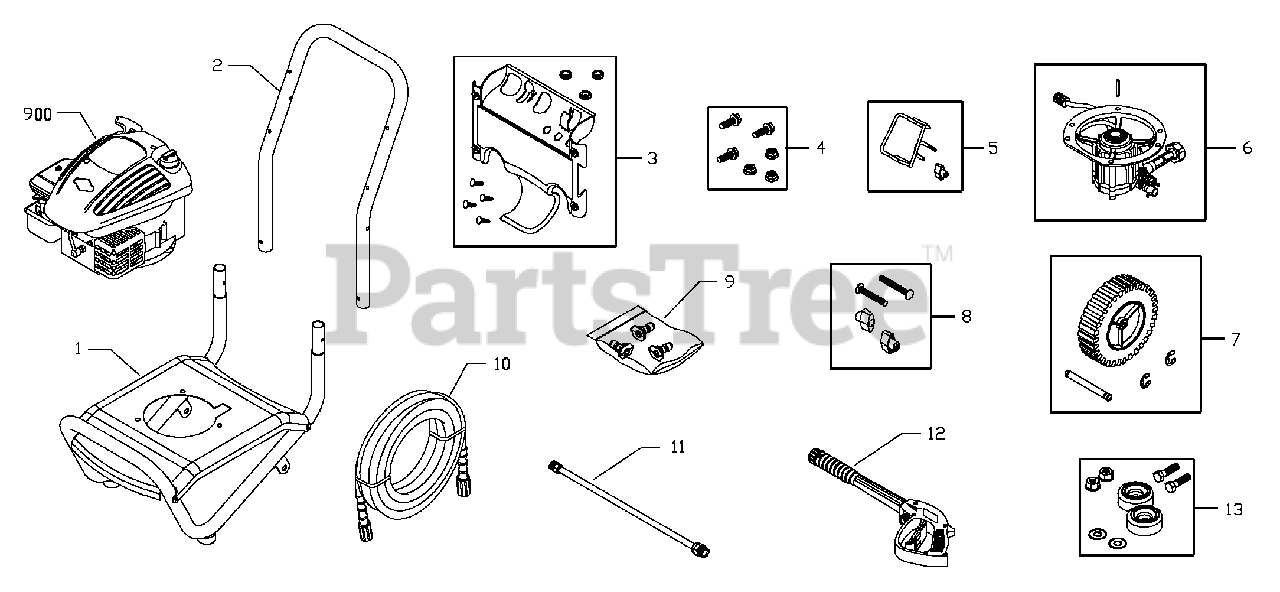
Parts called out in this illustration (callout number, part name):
2	HANDLE
3	KIT, Billboard w/Decals & Clips
4	KIT, Pump Mounting Hardware
5	KIT, Gun Holder
8	KIT, Handle Connector
10	HOSE, 25
11	EXTENSION
12	GUN
13	KIT, Vibration Mount
900	ENGINE
